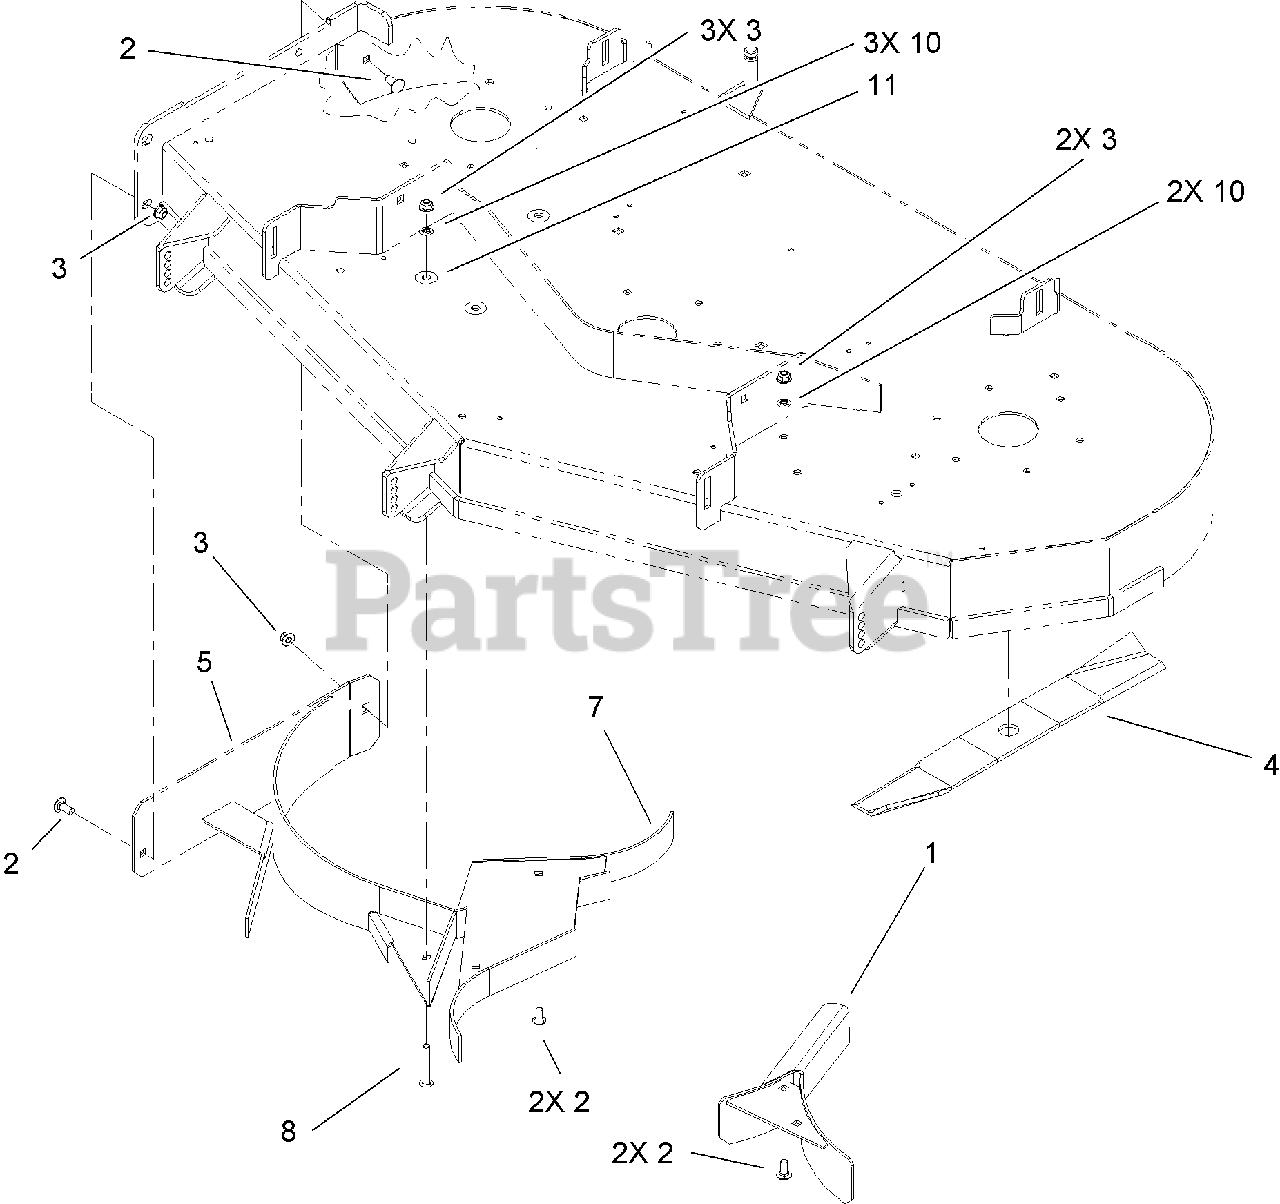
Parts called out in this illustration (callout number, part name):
1	LH MULCH BAFFLE ASM
2	SCREW-CARR
3	NUT-FLANGE, NI
4	BLADE-MULCH
5	RH MULCH BAFFLE ASM
7	CENTER BAFFLE ASM
8	SCREW-CARR
10	RING-BOLT RETAINING
11	DECAL-HOLE COVER
